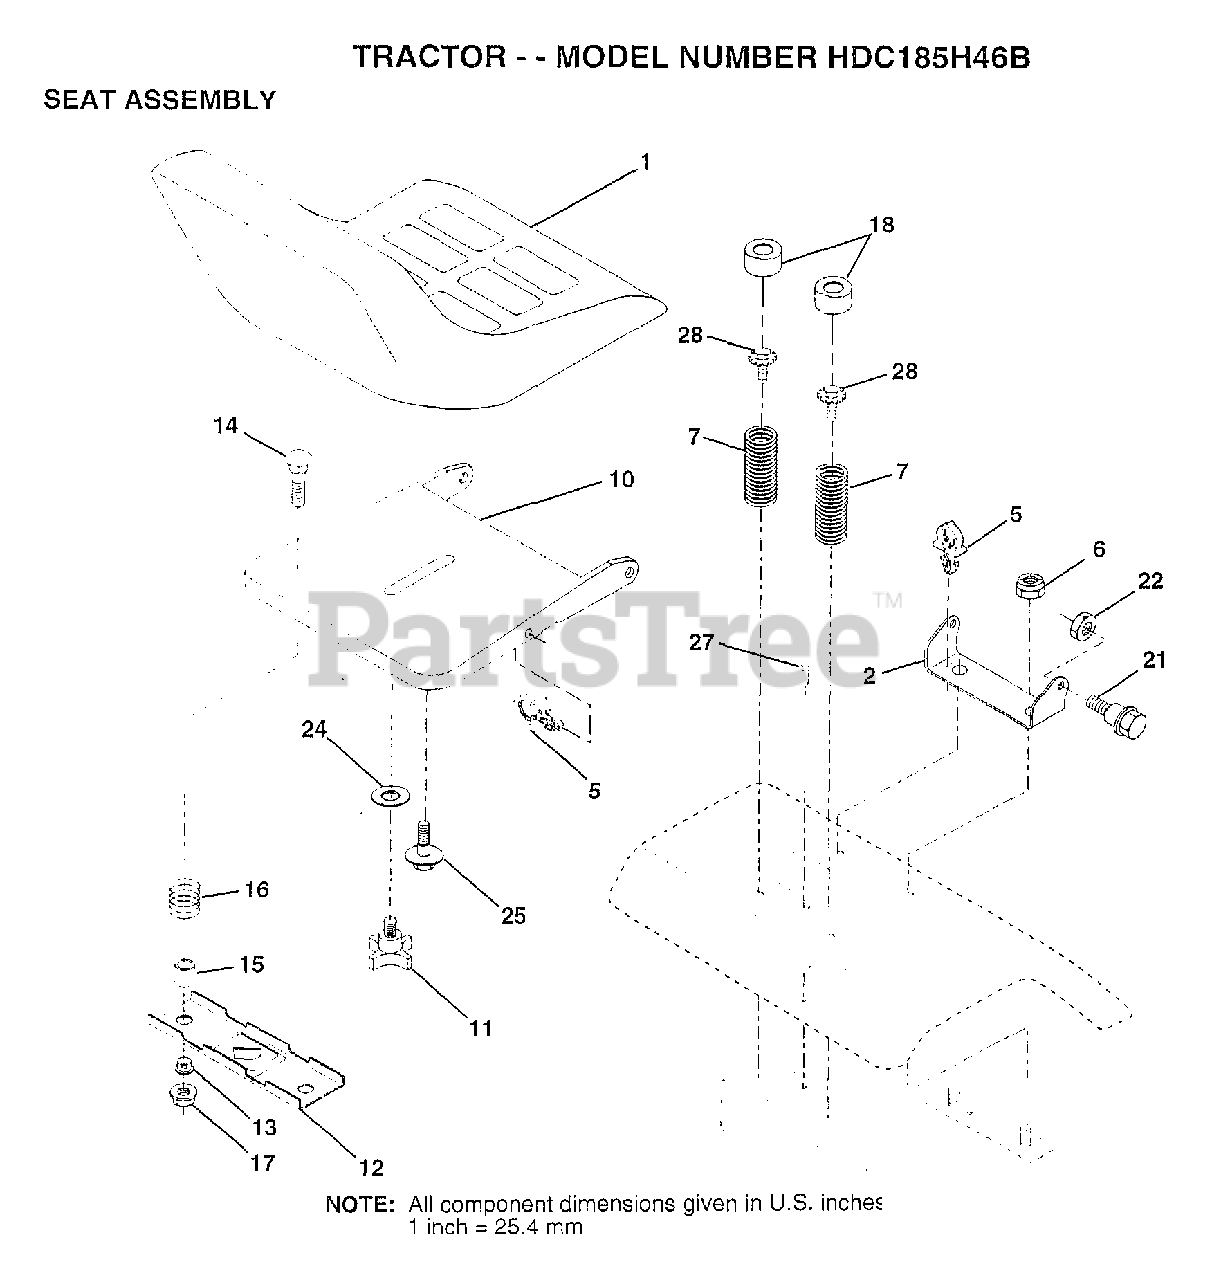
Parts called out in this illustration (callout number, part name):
1	SEAT.2500/1516.BK
2	BRACKET PVT SEAT
5	CLIP.PUSH-IN.HING
6	NUT
7	SPRING COMPRESSIO
10	PAN-SEAT
11	"KNOB 1/2"" YT"
12	BRKT SWITCH
13	BUSHING
14	BOLT-RD HD SQ NK
15	SPACER SPLIT
16	SPRING COMPRESSED
18	CAP SPRING
21	"BOLT,SHOULDER"
22	NUT
24	WASHER
25	"BOLT,SHOULDER"
27	SCREW LT
28	BOLT.5/16-18.UNC
